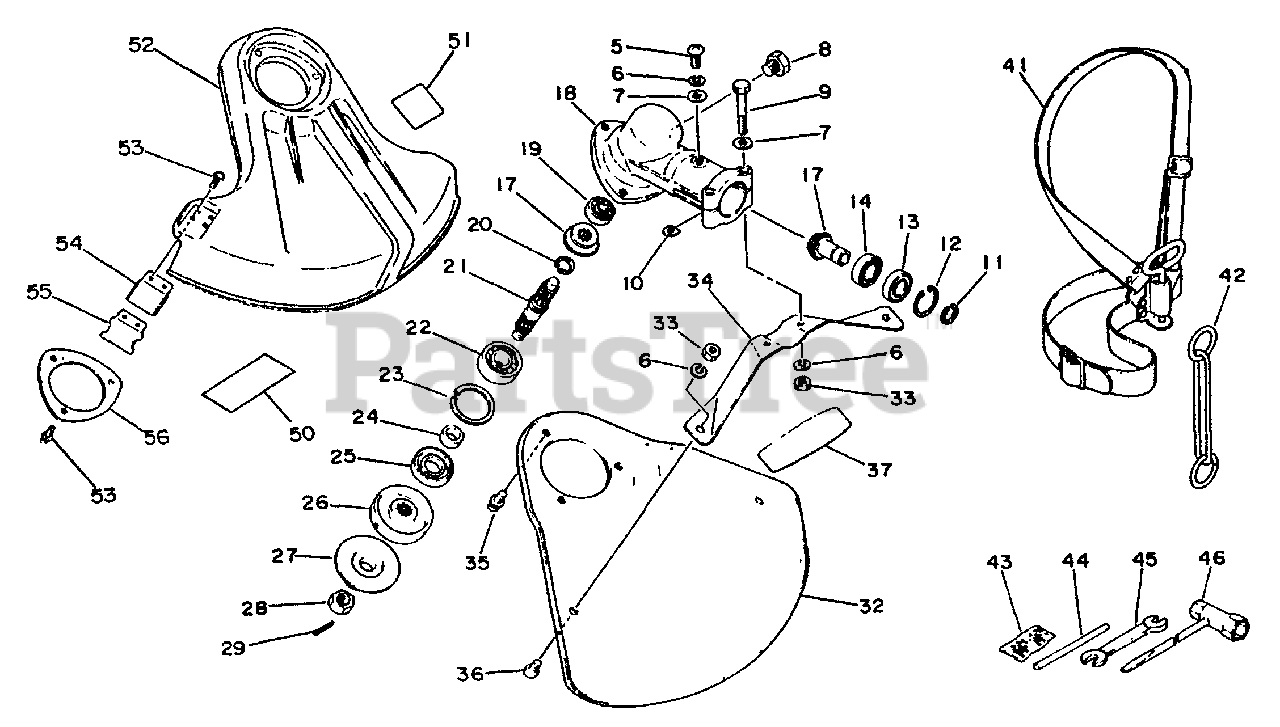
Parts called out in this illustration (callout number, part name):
5	SCREW - 5X10
6	LOCKWASHER - 5
7	WASHER - 5
8	BOLT - 8X8
9	BOLT - 5X35
10	WASHER
11	RING, RETAINING - 12
12	RING, RETAINING - 22
13	BEARING, BALL - 6900Z
14	BEARING, BALL - 6900
17	GEAR SET - BEVEL
18	CASE, GEAR
19	BEARING, BALL - 609
20	RING, RETAINING
21	GEAR - SHAFT
22	BEARING, BALL - 6201
23	RING, RETAINING - 32
25	SEAL, OIL
26	ADAPTOR, BLADE - UPPER
27	ADAPTOR, BLADE - LOWER
28	NUT - 10 -- LEFT HAND
29	PIN, SPLIT - 2X22
32	SHIELD ASSY - PLASTIC
34	BRACKET, SHIELD
35	SCREW - 5X10
36	SCREW - 5X8
37	LABEL - ECHO
41	SHOULDER STRAP ASSY
43	PIN, SPLIT - 2X22
44	LOCKING TOOL
45	SPANNER - 8X10mm
46	T-WRENCH - 17X19mm
50	LABEL - ECHO
51	LABEL - CAUTION
52	SHIELD, DEBRIS - PLASTIC
53	SCREW - 5X16
54	KNIFE, TRIMMER LINE
55	GUARD
56	PLATE, SHIELD
